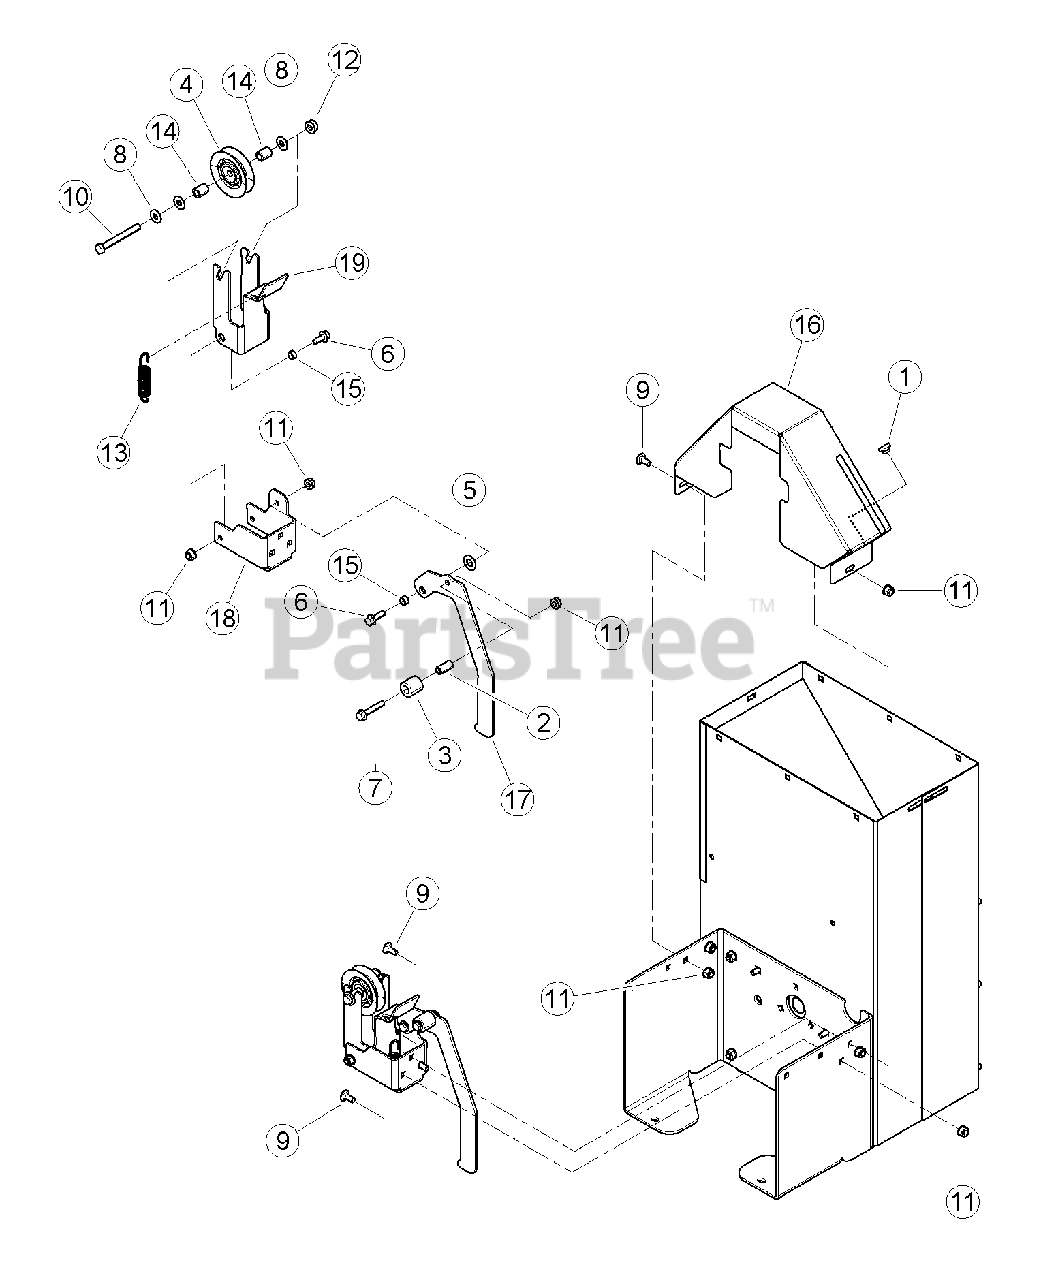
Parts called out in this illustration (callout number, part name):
1	BUMPER, RUBBER
2	SPACER, 0.5 X 1.00
3	ROLLER, 0.5 X 1.00 X 1.00 NYLON
4	IDLER, INSIDE
5	WASHER, 1/2 INCH NYLON
6	BOLT, 5/16 X 7/8 FLANGE NC
7	BOLT, 5/16 X 1-3/4 FLANGE NC
8	WASHER, 5/16" FLAT ZP
9	BOLT, 5/16 X 3/4 GR5 NC ZP CRG
10	BOLT, 3/8 X 3-1/4 HXHD GR5 ZP
11	NUT, 5/16-18 NYLOCK-FLANGE
12	NUT, 3/8-16 NYLOCK FLANGE
13	SPRING, 3/4" OD EXTENSION
14	SPACER, 3/4" LONG IDLER TUBE
15	SPACER, .50 X .25
16	SHIELD, UPPER
17	HANDLE, ENGAGEMENT
18	MOUNT, IDLER BRACKET
19	BRACKET, IDLER 3 IN CHIPPER
